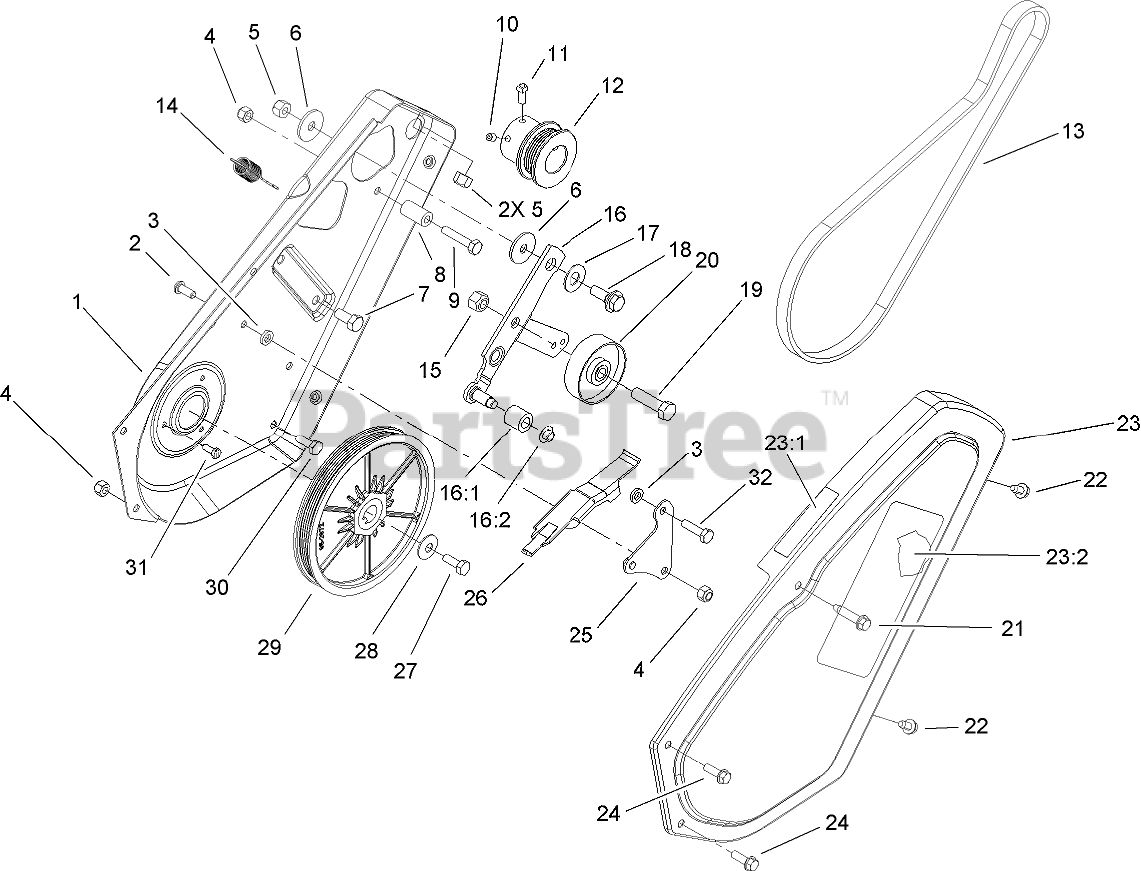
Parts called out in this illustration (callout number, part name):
1	PLATE-SIDE, LH
2	SCREW-HSBH
3	SPACER-PLATE, PIVOT
4	NUT-LOCK, NI
5	NUT-LOCK, NI
6	WASHER-PIVOT
7	SCREW-HH
8	SLEEVE-GUIDE, BELT
9	SCREW-HH
10	SCREW-HSH
11	SCREW-SQH
12	PULLEY-ENGINE
13	BELT-DRIVE
14	SPRING-EXTENSION
15	NUT-LOCK, CONE
16	IDLER ARM ASM
16:1	ROLLER-BRAKE
16:2	NUT-PUSH
17	WASHER
18	SCREW-SHOULDER
19	SCREW-HH
20	PULLEY-IDLER
21	SCREW-HWH
22	SCREW
23	COVER-DRIVE
23:1	DECAL-WARNING
23:2	DECAL
24	SCREW-HWH
25	PIVOT PLATE ASM
26	BRAKE-ARM
27	SCREW-HH
28	WASHER-BELLEVILLE
29	PULLEY ROTOR ASM
30	SCREW-HH
31	SCREW-SHH
32	SCREW-HH
